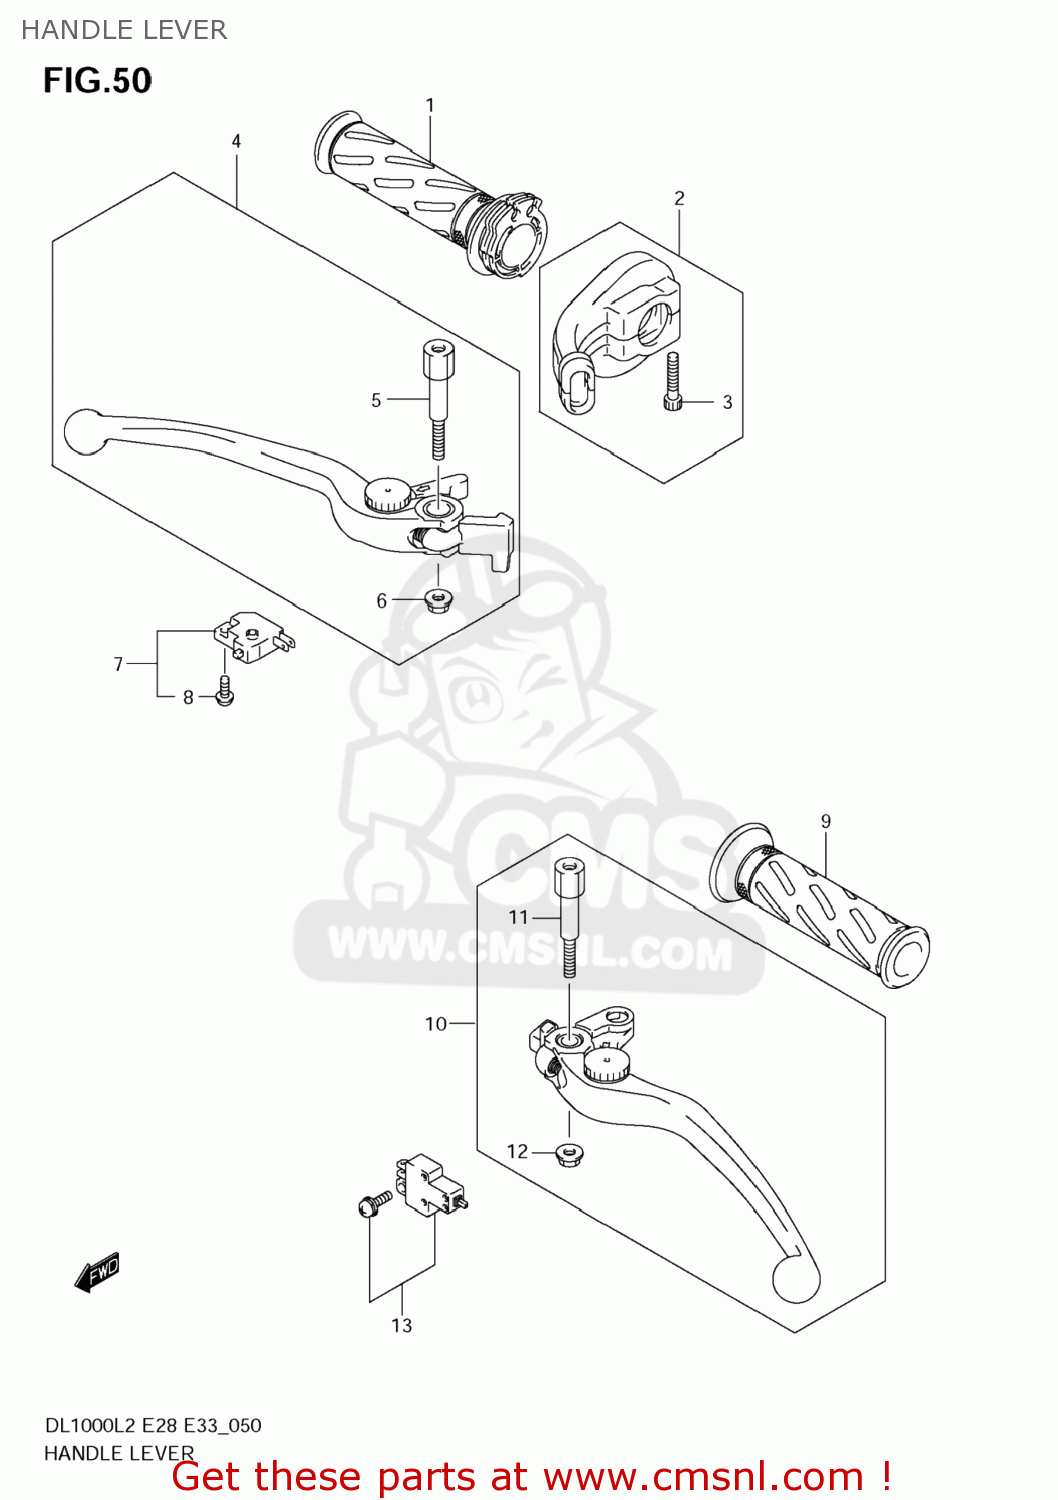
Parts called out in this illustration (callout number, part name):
1	GRIP,THROTTLE
2	CASE ASSY,THROTTLE
3	BOLT
4	LEVER ASSY,BRAKE
5	BOLT,LEVER
6	NUT
7	SWITCH ASSY,ST
8	SCREW
9	GRIP,L
10	LEVER ASSY,CLUTCH
11	BOLT,LEVER PIVOT
12	NUT
13	SWITCH ASSY,CLUTCH
